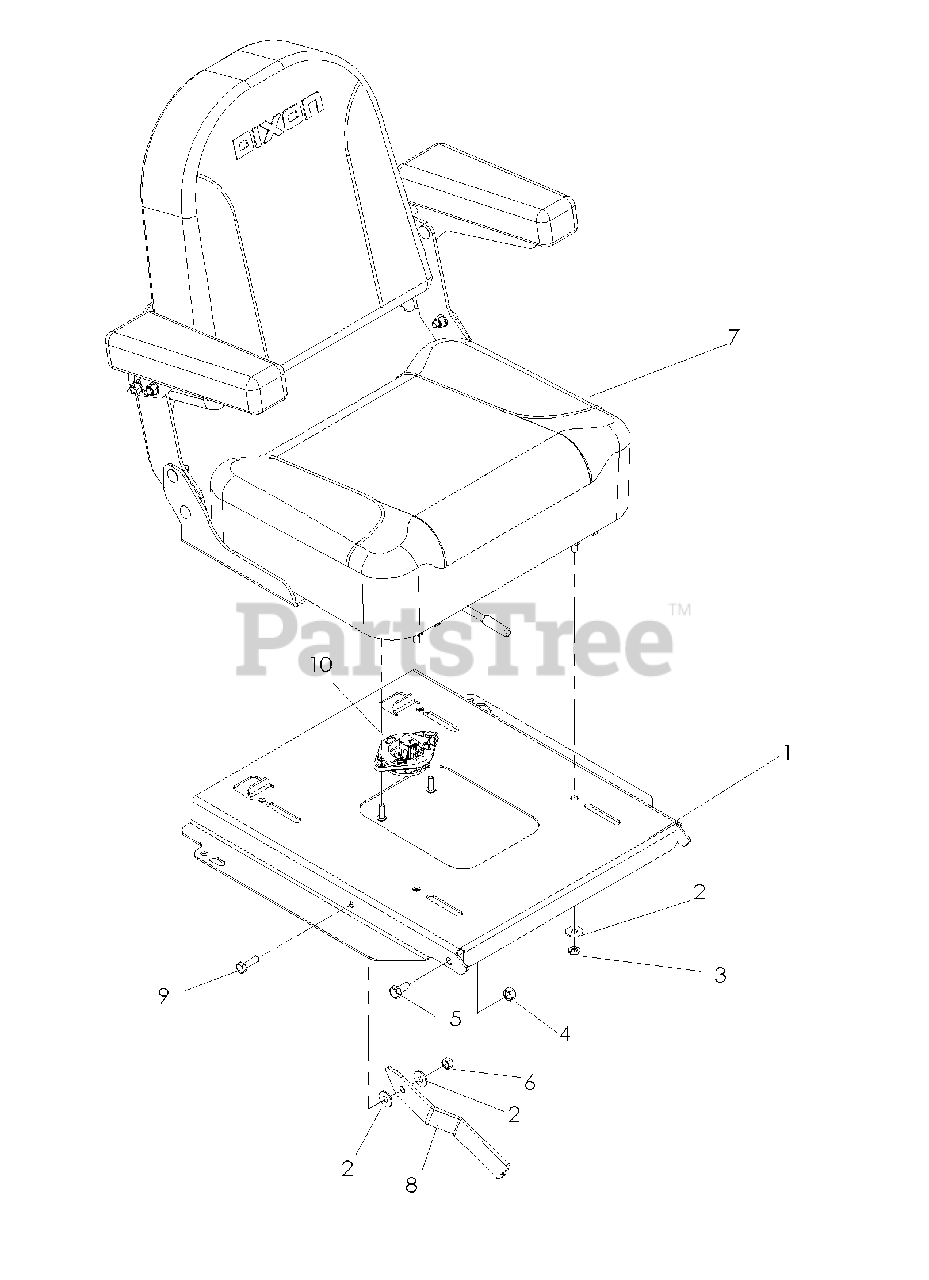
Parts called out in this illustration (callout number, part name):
1	PAN, SEAT, BLK
2	WASHER 5/16 FLAT
3	WASHER 5/16 LOCK
4	NUT 3/8-16 NYLOC
5	SCREW 3/8C X 3/4 HEX CAP
6	NUT 5/16 NYLOC
7	SEAT ASM W/SLIDE
8	ARM, PROP, SEAT
9	HCS 5/16C X 1
10	SEAT SWITCH MILSCO
11	SCR 1/4-20X3/4 SLTD RDHD GR2ZD
